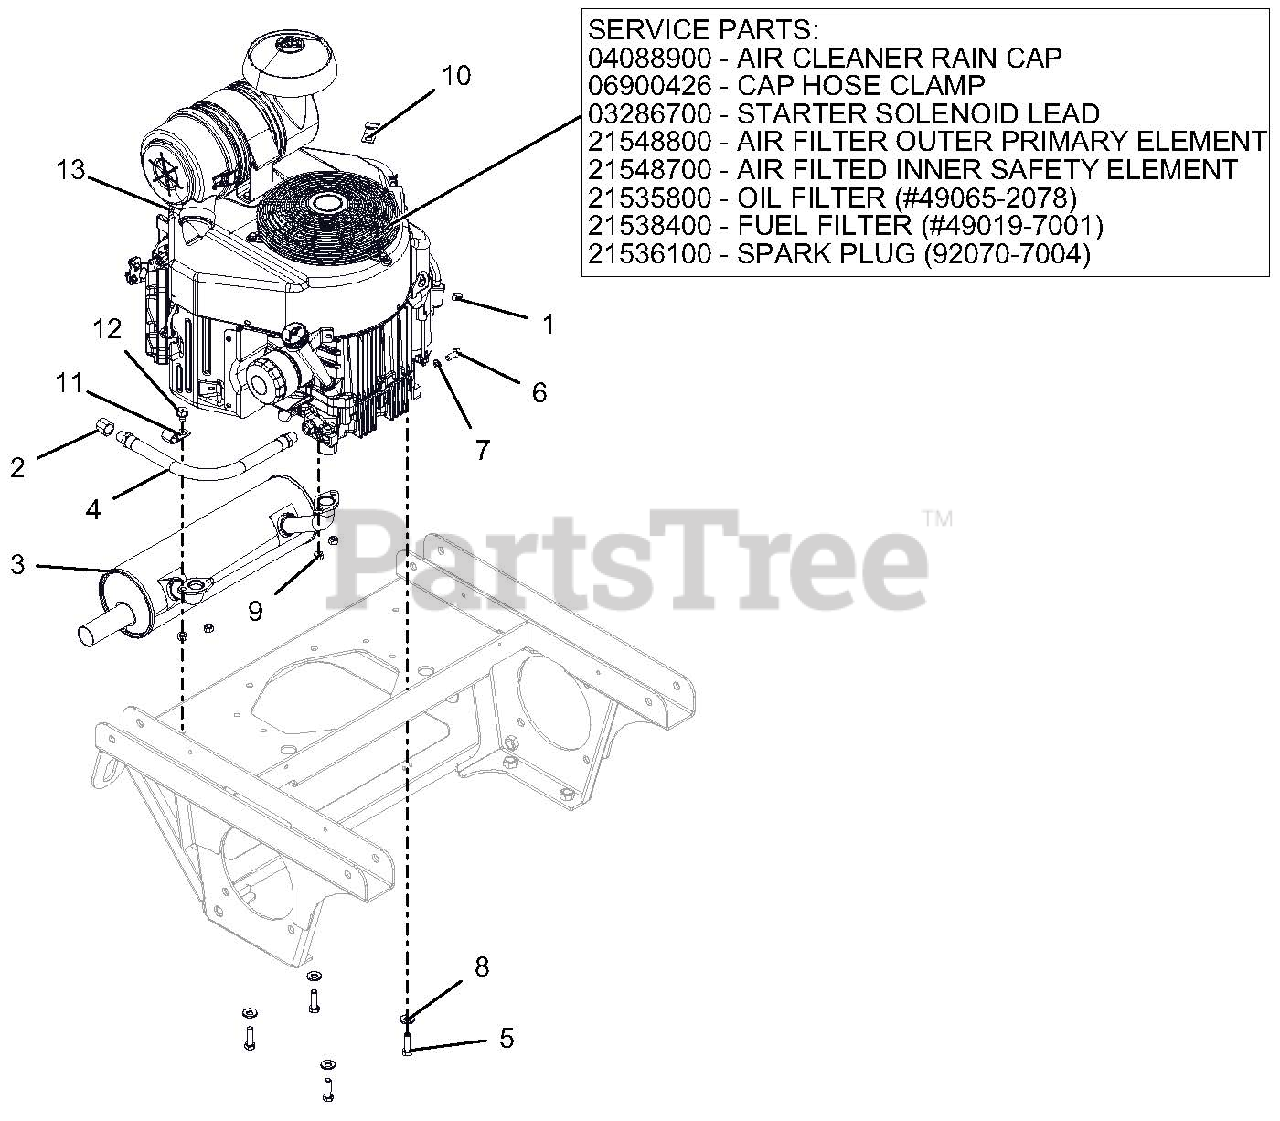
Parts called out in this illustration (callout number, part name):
1	CLAMP, FUEL LINE
2	PIPE CAP 3/8 NPT FEMALE
3	MUFFLER, KAWASAKI FX 24/26HP
4	HOSE,HYD .38-14-0K M6N0-M6N0
5	BLT-HEX.38-16X1.25 G5YZ NYTORQ
6	@BLT-HEX M8-1.25X20 YWZC
7	@WSHR-LK .31X.078 REG YWZC
8	WASHER, 3/8" SPRING DISC
9	NUT-LK-TOP M8-1.25 YWZC
12	@SCR-TAP .38-16X.50 HWH TR YWZ
13	ENGINE, KAWASAKI FX730
13	CAP, KAW 11065-7025
13	CLAMP, HOSE #36 SS 1.813-2.75
13	LEAD - STARTER SOLENOID
13	FILTER, OUTER
13	FILTER, INNER - KAW
13	FILTER,OIL - KAW
13	FUEL FILTER - KAWASAKI
13	PLUG, SPARK
